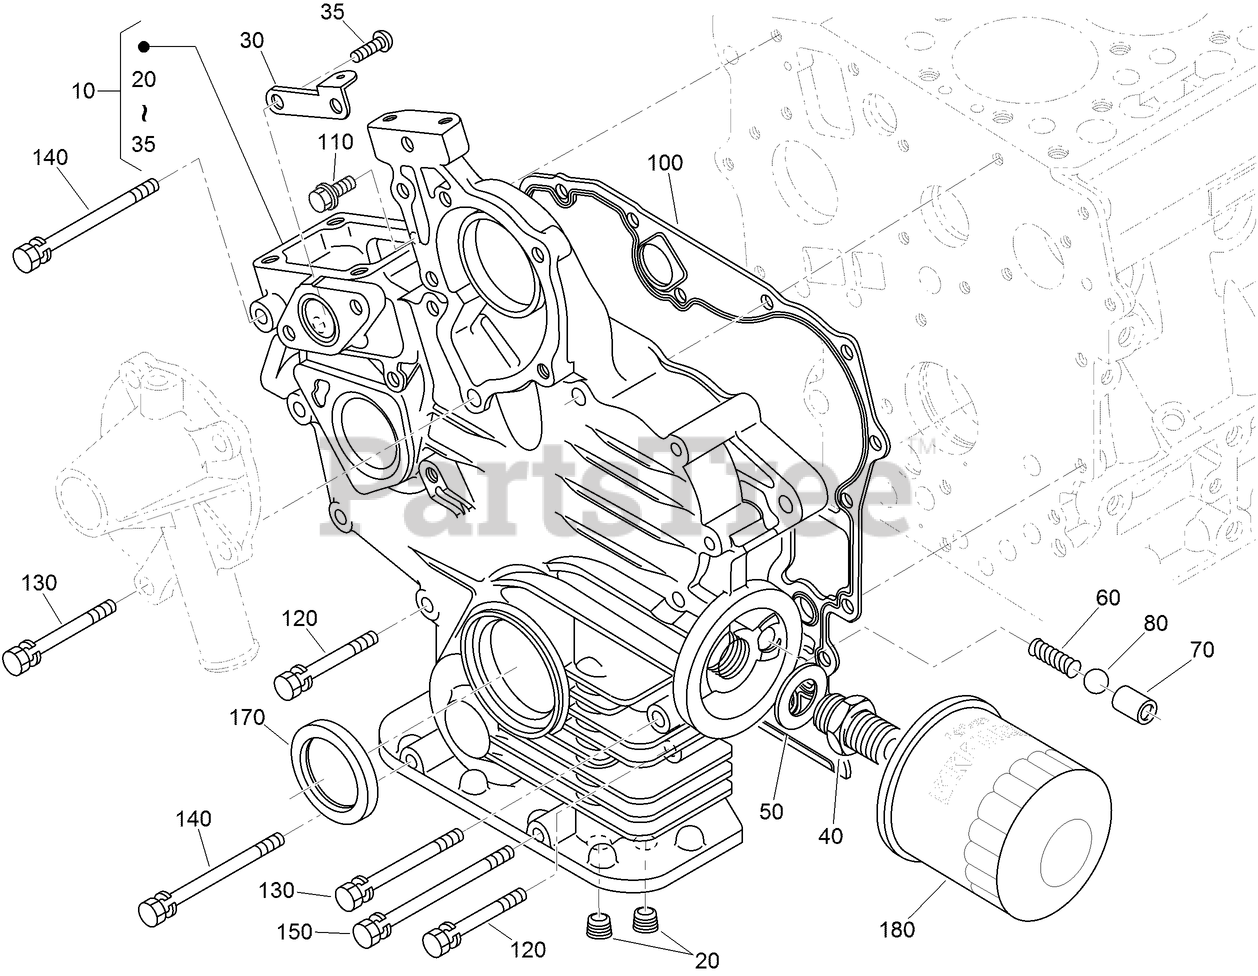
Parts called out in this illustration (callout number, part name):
10	GEAR CASE ASM
30	STAY-SPRING, START
40	JOINT-PIPE
50	WASHER-PLAIN
60	SPRING
70	SEAT-VALVE
100	GASKET-CASE, GEAR
110	BOLT-FLANGE
120	BOLT-SEMS
170	SEAL-OIL
180	FILTER-OIL, ENGINE
